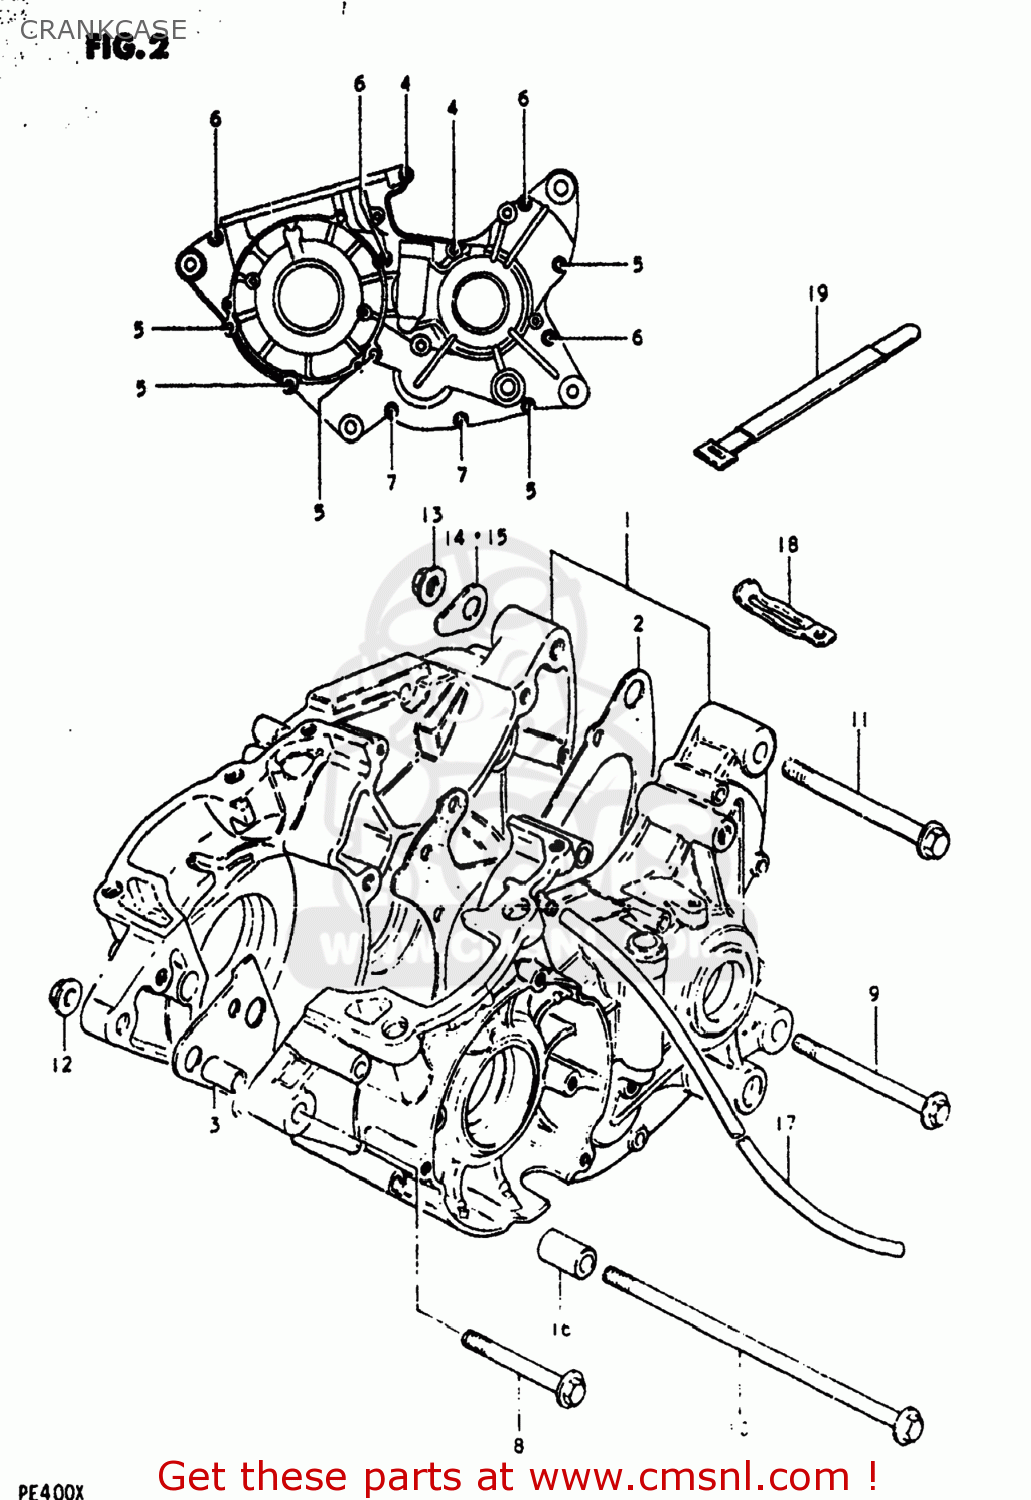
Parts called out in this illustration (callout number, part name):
1	CRANKCASE SET
2	GASKET,CRANKCASE (MCA)
3	PIN
4	CROSS SCREW (6 X 75)
5	SCREW 6X60
6	SCREW
7	SCREW (6X35)
8	BOLT(8X67)
9	BOLT
10	BOLT
11	BOLT
12	NUT
13	NUT
14	WASHER
15	WASHER
16	SPACER(8.6X16X26)
17	HOSE
18	CLAMP
19	CLAMP
